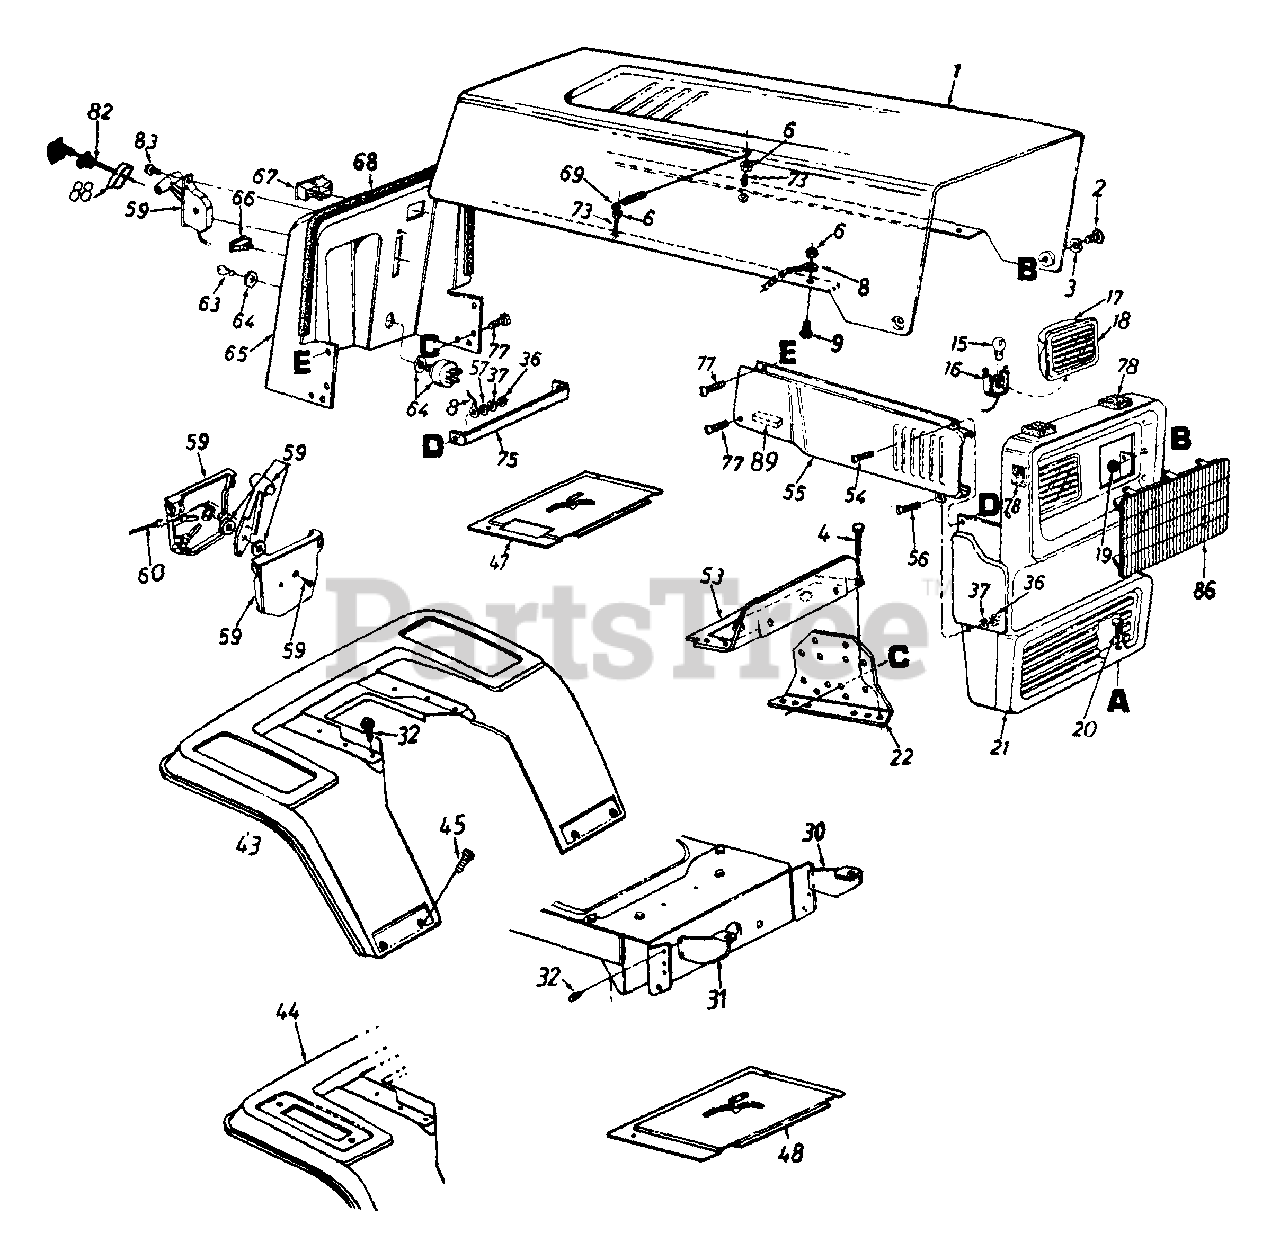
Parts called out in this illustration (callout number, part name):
3	Washer .39" I.D. x .62"
4	Hex Wash. Hd. B-Tap Scr. 5/16-18 x .5" Lg.
6	Hex Sems Nut #10-24 Thd.
8	Hood Stop
9	Truss Hd. Scr. #10-24 x 1/2"
15	Lamp
16	Twist Lock - Lamp Socket
17	Headlight Housing
18	Lens
19	L-Nut 1/4-28 Thd.
20	Hex Bolt 5/16-18 x .75" Lg.
30	Grille Mount Brk't. - L.H.
36	Hex Nut 1/4-20 Thd.
37	L-Wash. 1/4" I.D.
45	Truss Mach. Scr. 1/4-20 x .5" Lg.
47	Transmission Panel w/ Cutout
53	Fuel Tank Support
54	Truss Hd. Scr. 1/4-20 x .75"
57	Fl-Wash. .281" I.D. x .73" O.D.
59	Throttle Control Box Ass'y.
60	Throttle Control Wire (B&S)
63	Ignition Key
64	Ignition Switch
67	Ammeter
68	Trim Strip - 31"
69	Hood Spring
73	Hex Scr. #10-24 x 1.0" Lg.
75	Tie Strap - Grille/Side Panel
77	Hex Wash. Hd. Tap Scr. 1/4 x .75" Lg.
78	Foam Strip 3/8 x 1-1/8" x 1-1/2" Lg.
82	Choke Controls
83	Truss Mach. AB-Tap Scr. #10 x .5" Lg.
86	Headlight Bezel
88	Choke Retainer
89	Rubber Strip
